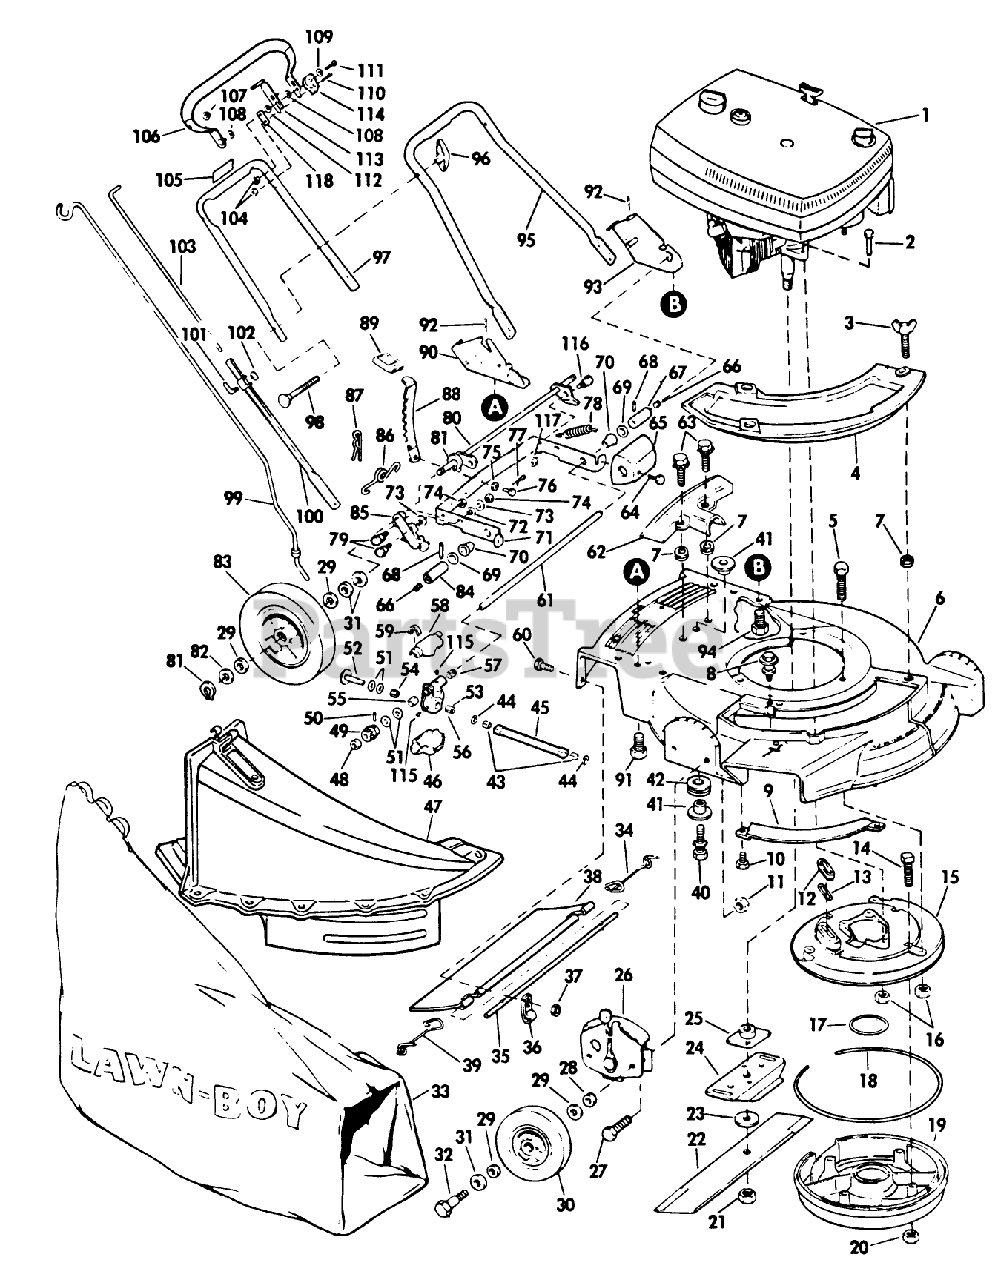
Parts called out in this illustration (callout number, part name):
1	Note #2 at bottom of this page.
2	BOLT F
3	WING SCREW LAWRE
5	SCREW V
9	BAR-TOE
11	NUT-LOCK F
12	SLEEVE
13	GASKET S
14	SCREW
16	NUT-LOCK F
18	Gasket Muffler (outside)
20	LOCKNUT E
21	NUT-BLADE
23	WASHER
25	PLATE AND COLLAR ASM
28	WASHER WROUGHT
29	WASHER
30	WHEEL & TIRE KIT
31	SPACER
32	BOLT WHEEL
33	ORD LB 89802 WHOLE GOODS
34	SPRIG T/SHLD ASOC
35	ROD 21" ADVANCE
36	CLAMP ROD KMC
37	LOCKNUT E
39	SPRING;TRAILING SHIELD RH
41	SPACER ECK PRES
42	GROMMET
43	BUSHING
44	O Ring
48	WASHER
50	ROLL PIN
51	THRUST WASHER
54	NEEDLE BEARING
58	GEAR COVER UPPER
61	DRIVE SHFT TAG AY
62	COVER
63	SCREW SEMS TRM HEX HD
65	GUARD
66	GREASE PLUG
68	PIN
73	WASHER S
74	STOP NUT
75	WASHER SPRING LAR
76	PIN
78	SPRING
79	BOLT RB&W
81	RET RING
82	SPACER
86	SPRING N.A.S
88	LEVER
89	KNOB
91	SCREW
92	HAIR PIN
94	SCREW
96	NUT-WING
97	HANDLE
99	ROD GRASSBAG
103	ROD CONTROL
104	LOCKNUT E
108	WASHER M
110	SCREW-HANDLE STOP
111	BOLT PIONEER
112	WASHER
113	LEVER LOCKOUT
115	**FITTING LINCOLN
116	BOLT RB&W
117	LOCKNUT E
118	HANDLE STOP
